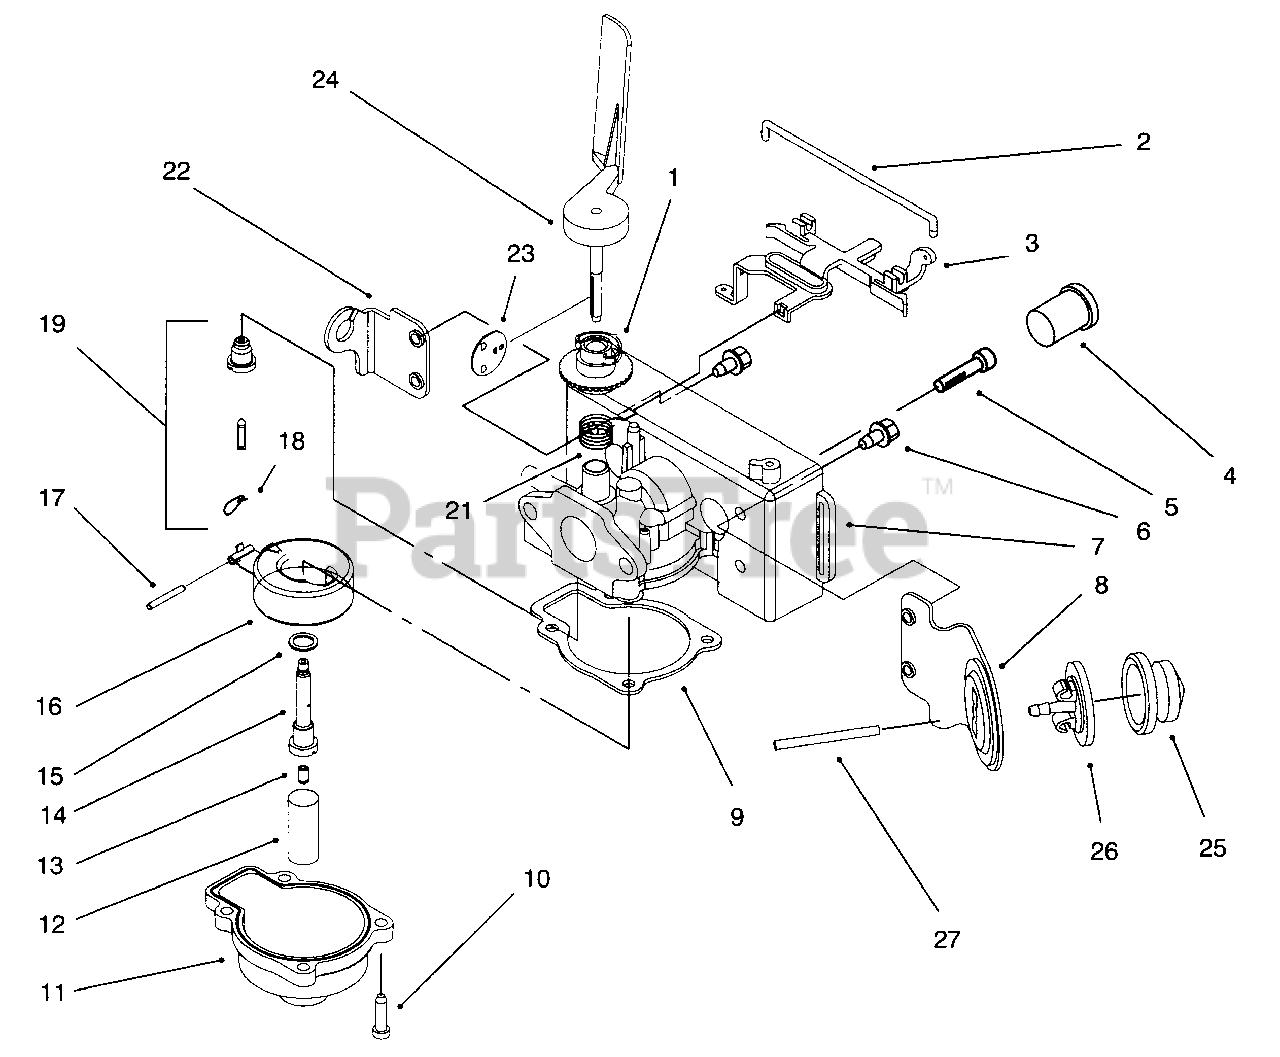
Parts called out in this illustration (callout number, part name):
1	Collar-Adjustment
2	Retainer
3	Lever-Speed Adjust
4	Plug
5	Screw-Pan Hd. Sems
7	Body-Carburetor
8	Bracket-Primer
9	Gasket-Float Chamber
11	Float Chamber
12	Filter-Fuel
13	Main Jet
16	Float & Arm Assembly
18	Clip
19	Float, Valve, & Body Ass'y
21	Spring-Governor
22	Bracket-Throttle Control
23	Disc-Throttle
24	Air Vane & Shaft
25	Bulb-Primer
26	Body-Primer
27	Hose-Primer
